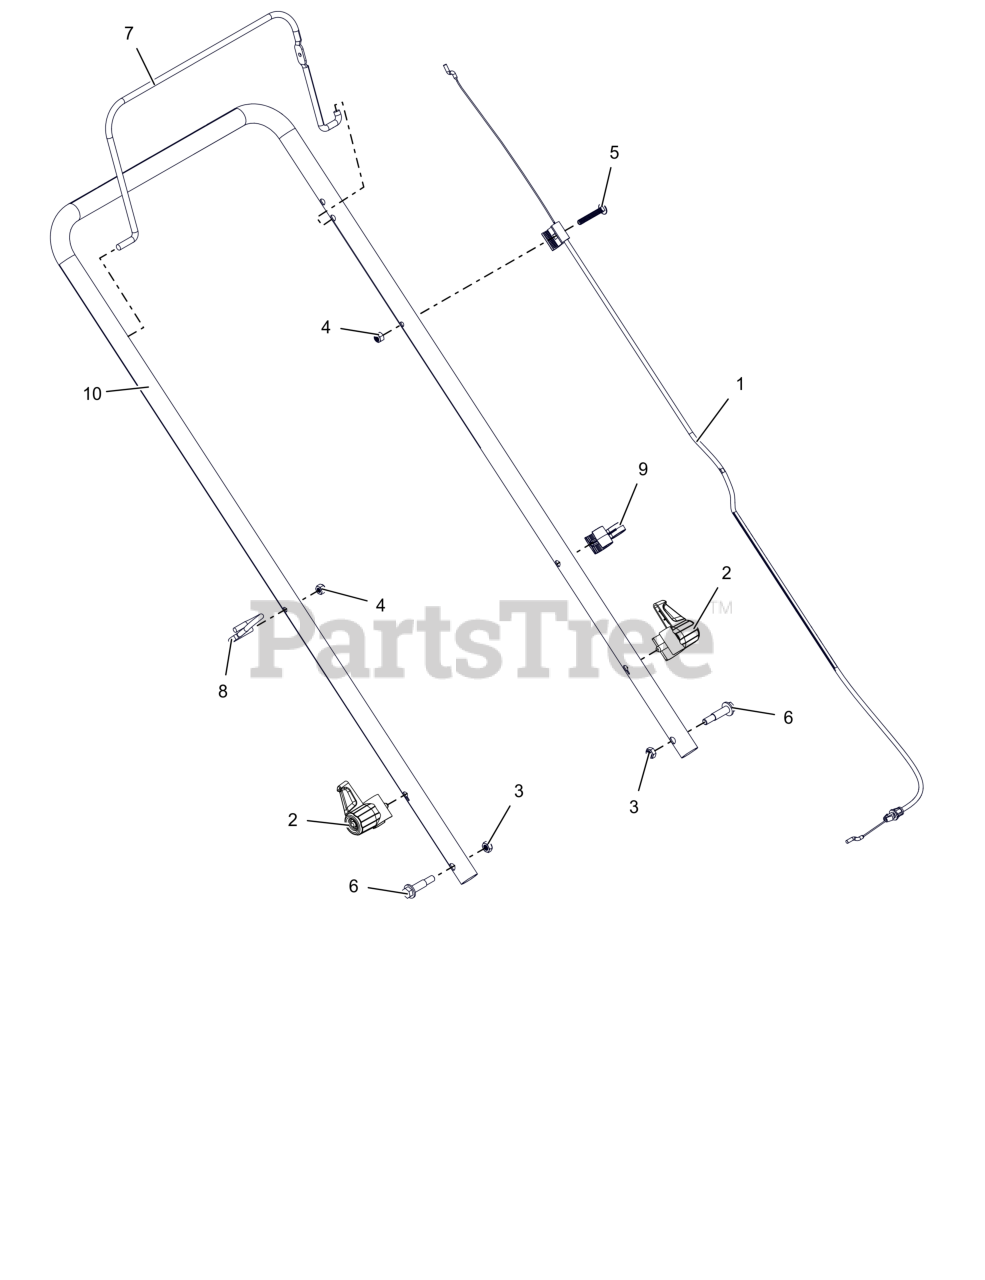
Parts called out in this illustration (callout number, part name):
1	CABLE, FWD OPC
2	ASM, HANDLE ADJUSTER
3	NUT, NYLOC 5/16-18
4	NUT, NYLOC 1/4-20
5	BOLT, CARRIAGE 1/4-20X1.75
6	BLT, SHLDR HWH .65X1.015X 5/16-18
7	BAIL, OPC -SP (GRAY)
8	GUIDE, STARTER ROPE (BLACK)
9	GUIDE, CABLE
10	HANDLEBAR, SELF PROPELLED (BLACK)
